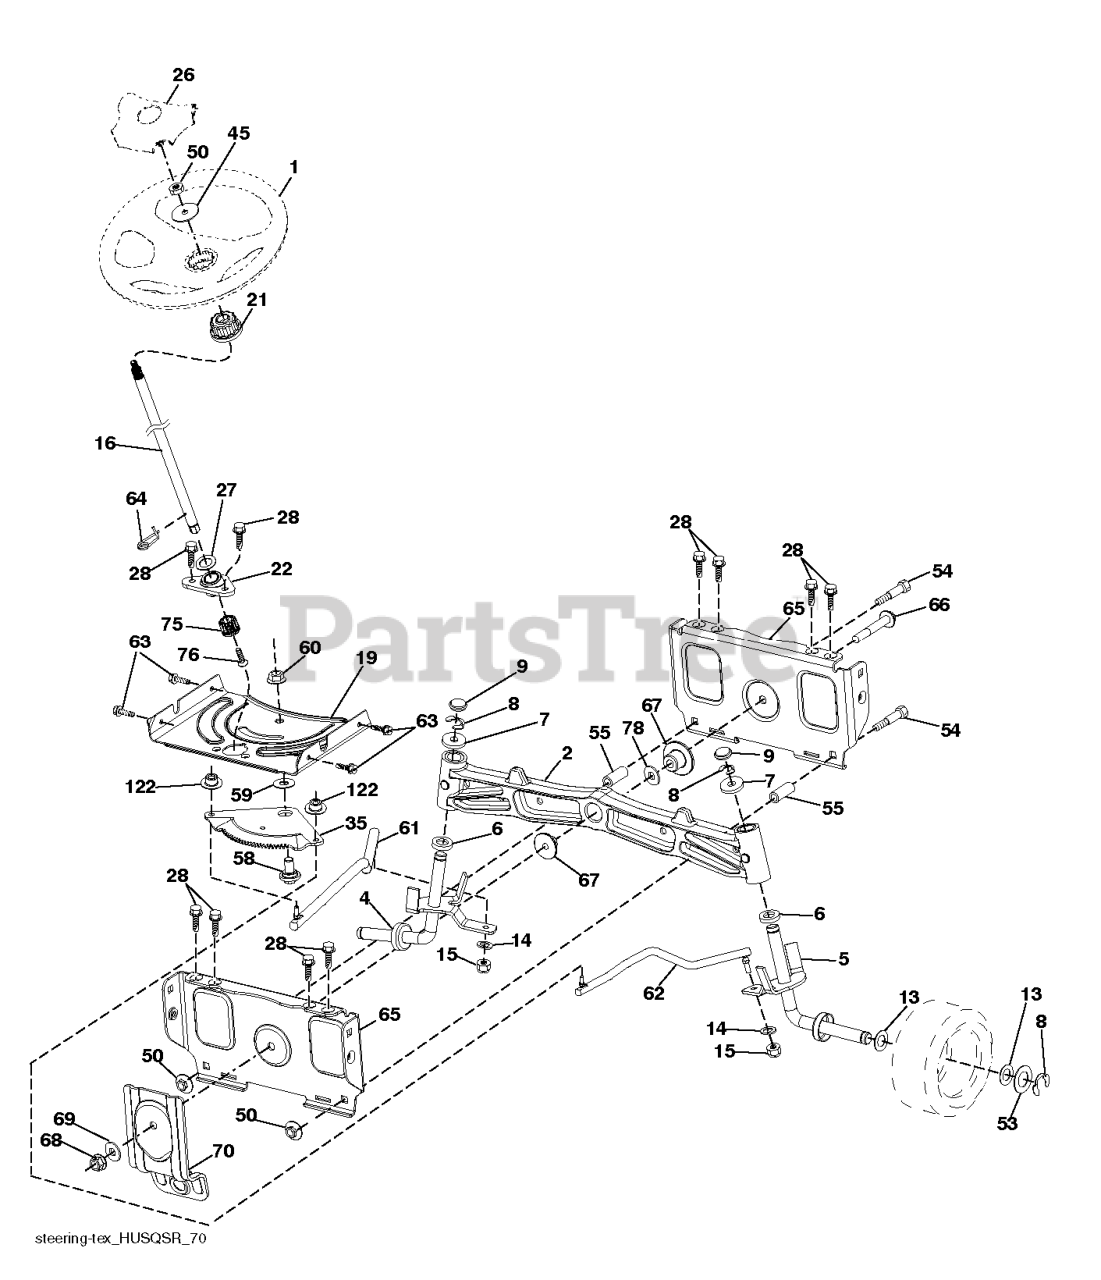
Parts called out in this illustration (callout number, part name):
1	WHEEL.STEER.HUSQ.SR.498.OVMLD
2	AXLE.CAST.IRON
4	SPINDLE.WELDED.LH.16"TEX
5	SPINDLE.WELDED.RH.16"TEX
6	THRUST WASHER
9	CAP.SPINDLE.BLACK
14	SLW 3/8 STD
15	NUT CROWNLOCK 3/8-24
16	SHAFT.STEER.2HIGH.SPLND.PLATED
19	PLATE.STEER.DDL.NLT/NG
21	ADAPTER.WHEEL.STEER.SPLND.ALUM
22	BEARING.SUBASM.SHAFT.STEER.LOW
26	INSERT.CAP.WHL.STRG.HUSQ.PREM
27	WASHER LT
28	SCREW, 3/8-16X3/4
35	GEAR.SECTOR.PLATE.DDL.
45	WASHER.3/8ID.2-3/8OD.12GA.PLTD
50	NUT LOCK FLG 3/8-16 UNC
53	WASHER.HARDENED
55	SPACER.BRACE.AXLE
58	BOLT.SHOULDER.SECTOR.P
59	WASHER.THURST.SECTOR.S
60	NUT FLANGE LOCK 5/8-11
61	LINK.ASM.DRAG.ADJUST.LH.PLATED
62	LINK.ASM.DRAG.ADJUST.RH.PLATED
63	SCREW
64	RETAINER.CLIP.SPRING.S
65	BRACE.AXLE.FRONT.NLT/N
66	BOLT HEX FGHD 7/16-14 X 3 SERR
67	BUSHING.PM.FRONT AXLE
68	NUT.LOCK.FLANGE.7/16
69	WASHER.1.5X.505X.118
70	BRACKET.FRT.DECK.SUSP.RR.MT431
75	PINION.ZINC PLATED
76	SCREW HEAD SOCKET LRVB
78	THRUST WASHER
122	CAP.GEAR.SECTOR.TEX
